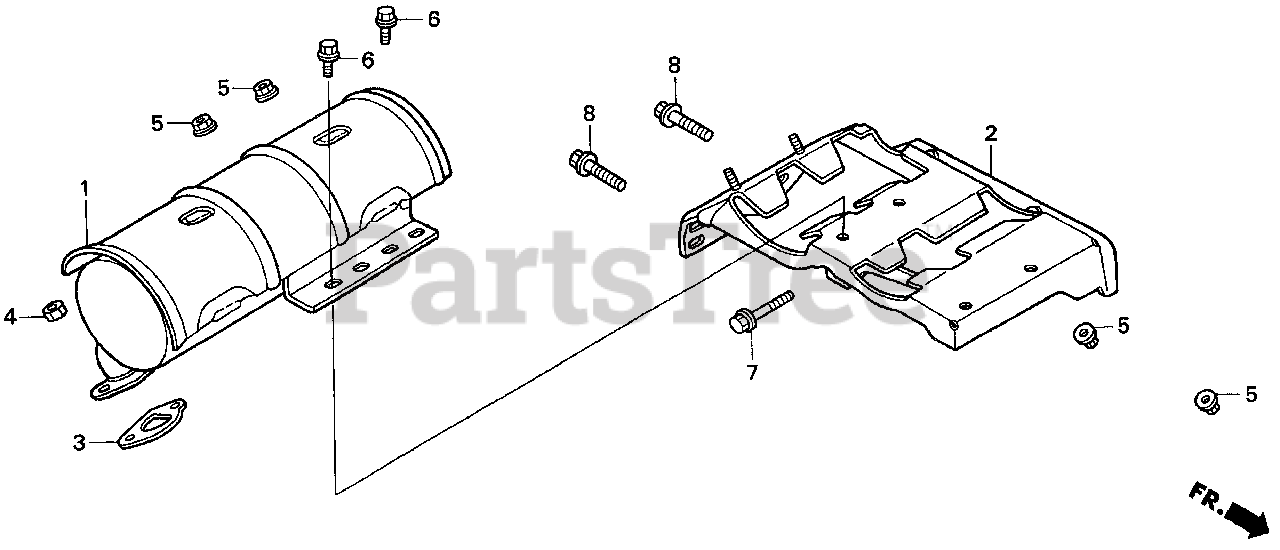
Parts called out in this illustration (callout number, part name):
1	MUFFLER
2	STAY, MUFFLER
3	GASKET, MUFFLER
4	NUT, HEX. (8MM)
5	NUT, FLANGE (6MM)
6	BOLT, FLANGE (6X16)
7	BOLT, FLANGE (6X25)
8	BOLT, FLANGE (8X20)
